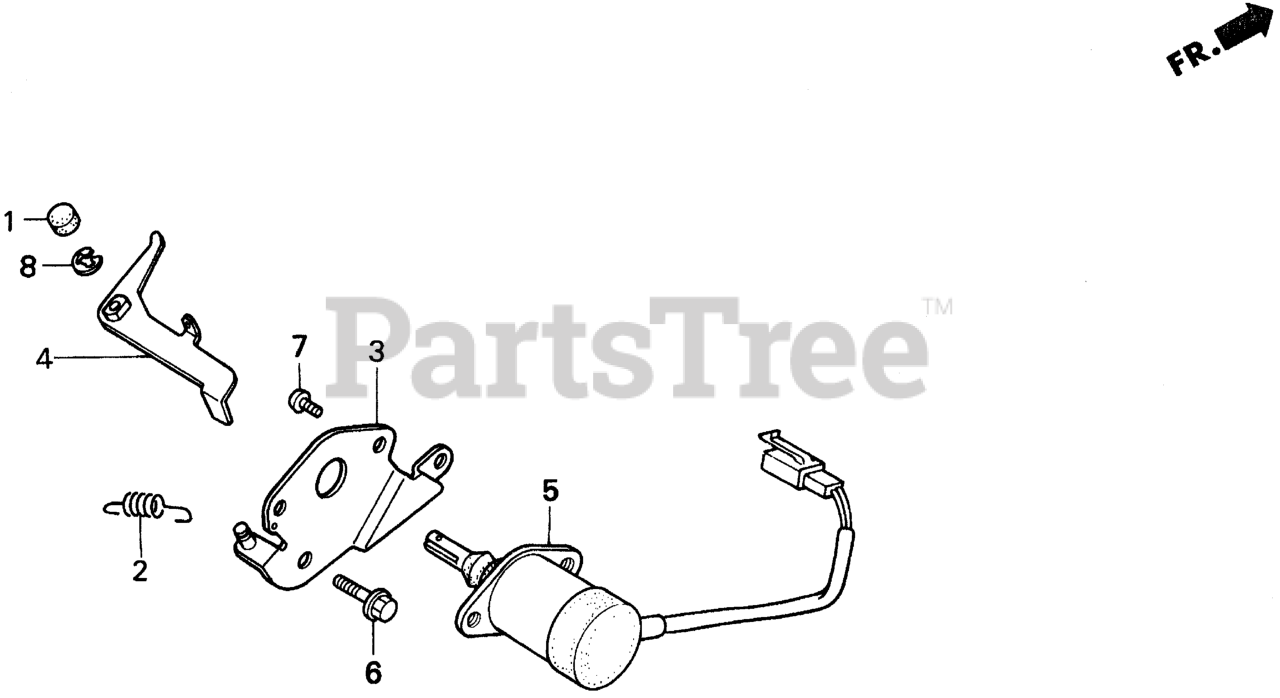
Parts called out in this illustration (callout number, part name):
1	CAP, CHOKE LEVER
2	SPRING, CHOKE RETURN
3	STAY, SOLENOID THROTTLE
4	LEVER, SOLENOID THROTTLE
5	SOLENOID ASSY.
6	BOLT, FLANGE (6X12) (CT200)
7	SCREW, PAN (5X8)
8	E-RING (4MM)
